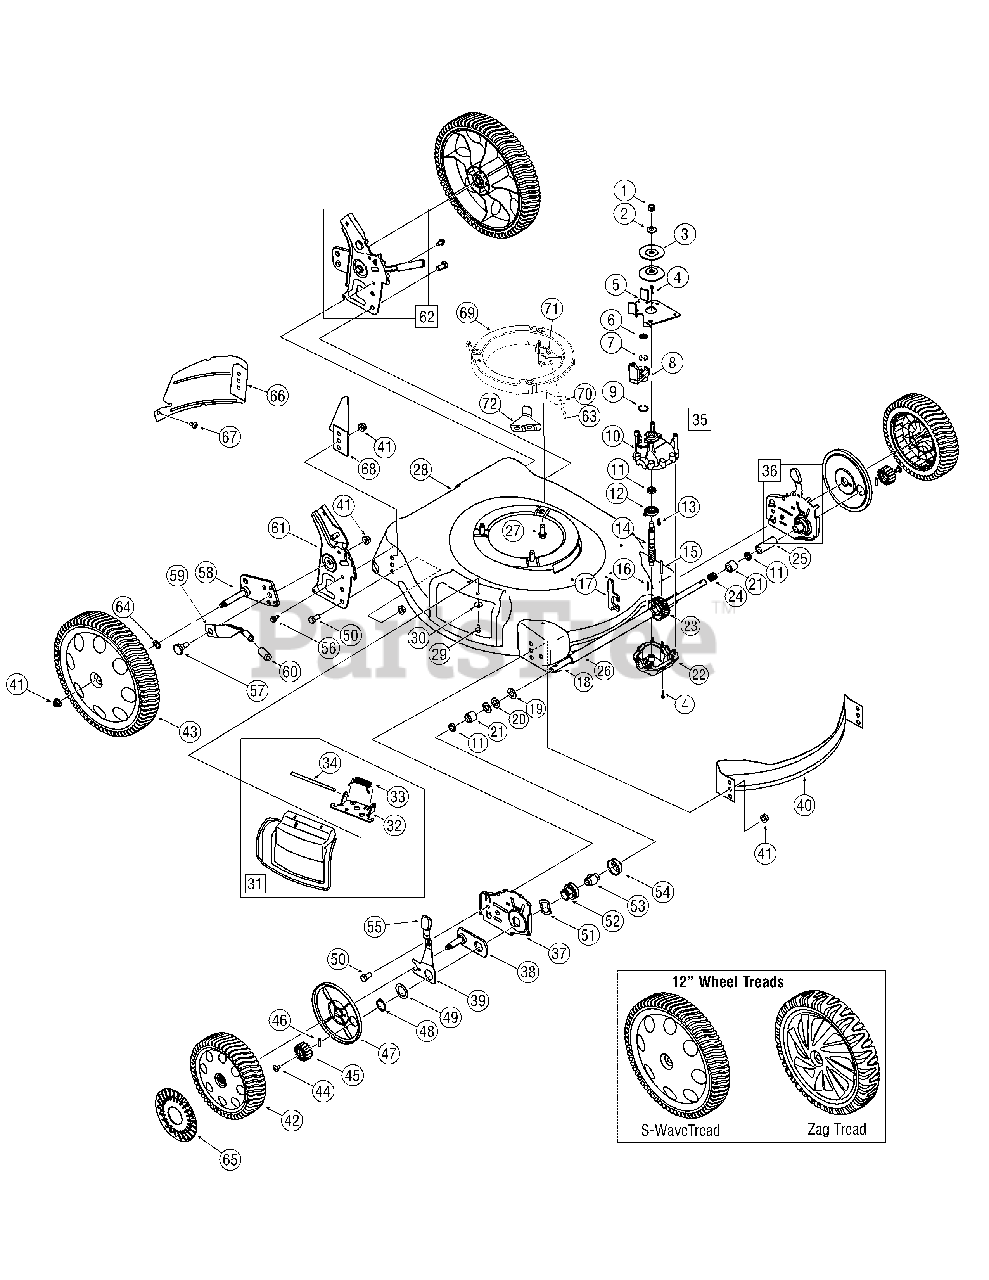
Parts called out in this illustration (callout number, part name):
1	Hex L-Nut 3/8-24
2	Cupped Washer
3	Pulley, 3.82 x .313 x .68
5	Transmission Bracket
6	Push Nut
7	Slotted Washer
10	Upper Housing
11	Oil Seal
18	Out put Shaft
19	Flat Washer
21	Plastic Bushing
22	Lower Housing Ass’y
23	28 Tooth Gear
24	Compression Spring
25	Sleeve Spacer 1.8" Lg.
26	Sleeve Spacer 9.10" Lg.
27	Hex Wash TT Sems Scr 3/8-16 x 1.875
29	Hex Wash S-Tapp Scr 1/4-20 x .50
30	Cupped Washer .265 ID x .75 OD x .062
31	Complete Mulch Plug
32	Chute Hinge
33	Torsion Spring
34	Hinge Pin
35	Transmission Ass’y Complete
36	RH Height Adjustment Assembly
36	LH Height Adjustment Assembly
37	Height Adjuster Plate - RH
37	Height Adjuster Plate - LH
38	Height Adjuster Pivot Plate Ass'y
39	Spring Lever Front RH
39	Spring Lever Front LH
40	Front Baffle
41	Hex L-FlangeNut 3/8-16 Gr. F, Ny lon
42	Wheel Ass'y 8 x 2.125 Gear Zag
43	Wheel Ass'y 12 x 2.125 Gear Zag
44	Pan Scr. 1/4-20 x .390
45	Spur Gear 14T RH
45	Spur Gear 14T LH
47	Wheel Dust Cap
48	Snap Ring for 1.0" shaft
49	Flat Washer 1.5 OD x .03
50	Hex Cap Screw 3/8-16 x .75
51	Wave Washer
52	Bearing Support
53	Bearing Sleeve
54	Bearing Retainer
55	Height Adjuster Knob
56	Hex Wash Hd TT Scr. 1/4-20 x .625
57	Shoulder Screw .50 Dia. X .385
58	Pivot Arm Assembly - RH
58	Pivot Arm Assembly - LH
59	Rear Spring Lever
61	RH Handle Bracket
61	LH Handle Bracket
62	LH Handle Bracket Assembly
62	RH Handle Bracket Assembly
64	Spring Washer .50 ID x 1.0 OD x .022
65	Hub Cap Grey Ra dial
66	LH Rear Baffle
67	Screw AB 1/4-14 x 0.625
68	RH Rear Baffle
69	Engine Spacer
70	Belt Keeper Bracket
72	Belt Keeper Bracket
